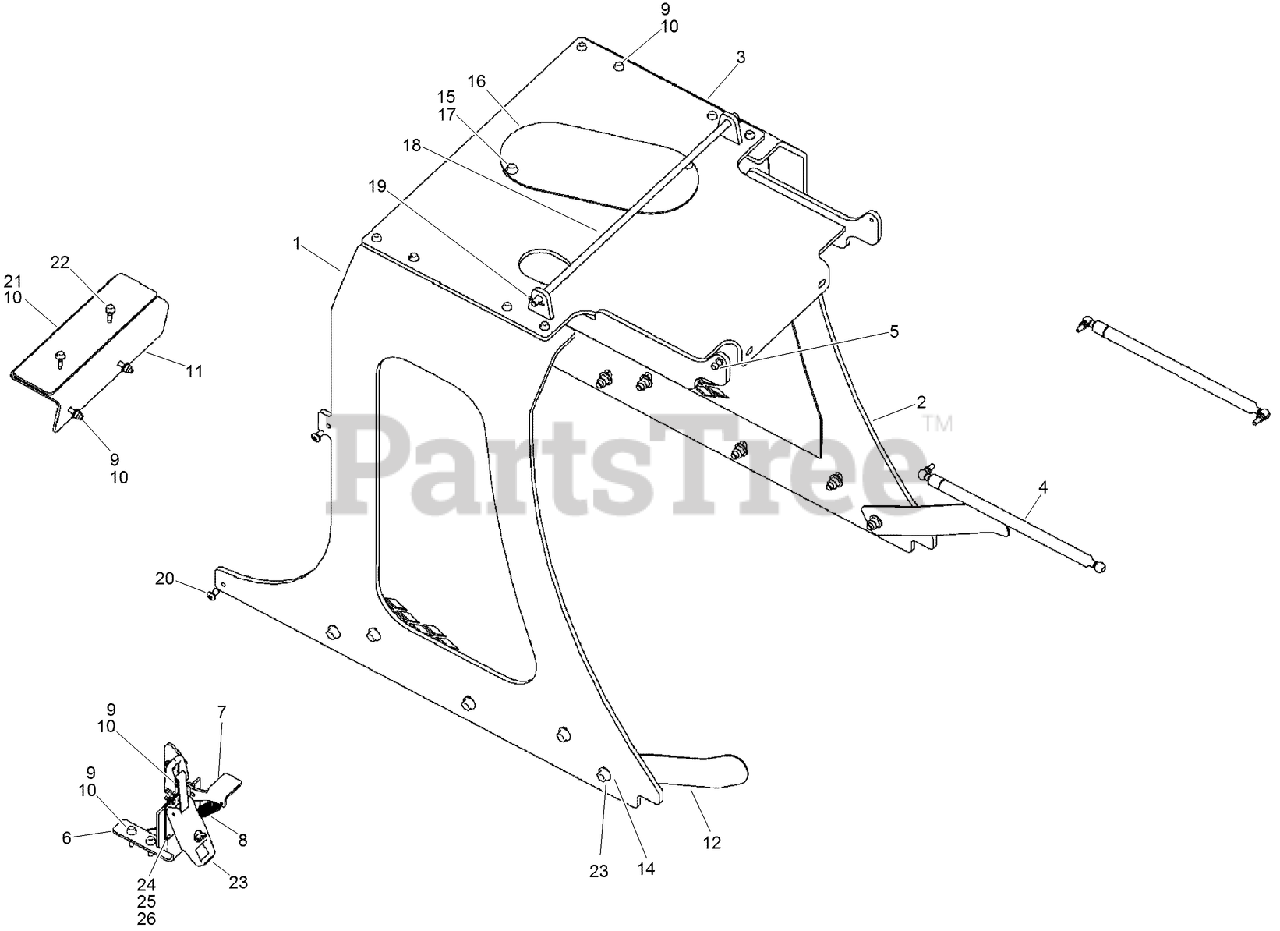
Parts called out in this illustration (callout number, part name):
1	PLATE - Mounting, Hood, Weldment
2	PLATE - Mounting, Hood, Weldment
3	WELDMENT - Hood Mounting
4	SPRING-GAS
5	STUD-BALL
6	MOUNT - Hood Safety Latch
7	LATCH - Hood Safety
8	SPRING-TENSION
9	SCREW, METRIC FLANGE w/BODY - M8 x 35
10	NUT-TORQUE, PREVAILING
11	PLATE - Rear Hood Stop
12	GUIDE - Hood
14	NUT-HHF, LOCK
16	PLATE - Cover
17	SCREW-FLANGE
18	PIN-MOUNT, HOOD
19	PIN - Cotter, 1/8 Dia x 1 Long
20	SCREW-HSH
21	PLATE - Sandwich
22	SCREW-HHF
23	LATCH - Lockable, Draw
24	SCREW - PHd Sltd # 10-24 x 0.75 CST ZND
25	WASHER - 0.219 x 0.438 x 0.049 in CST ZND
26	NUT-#10-24 KEPS
